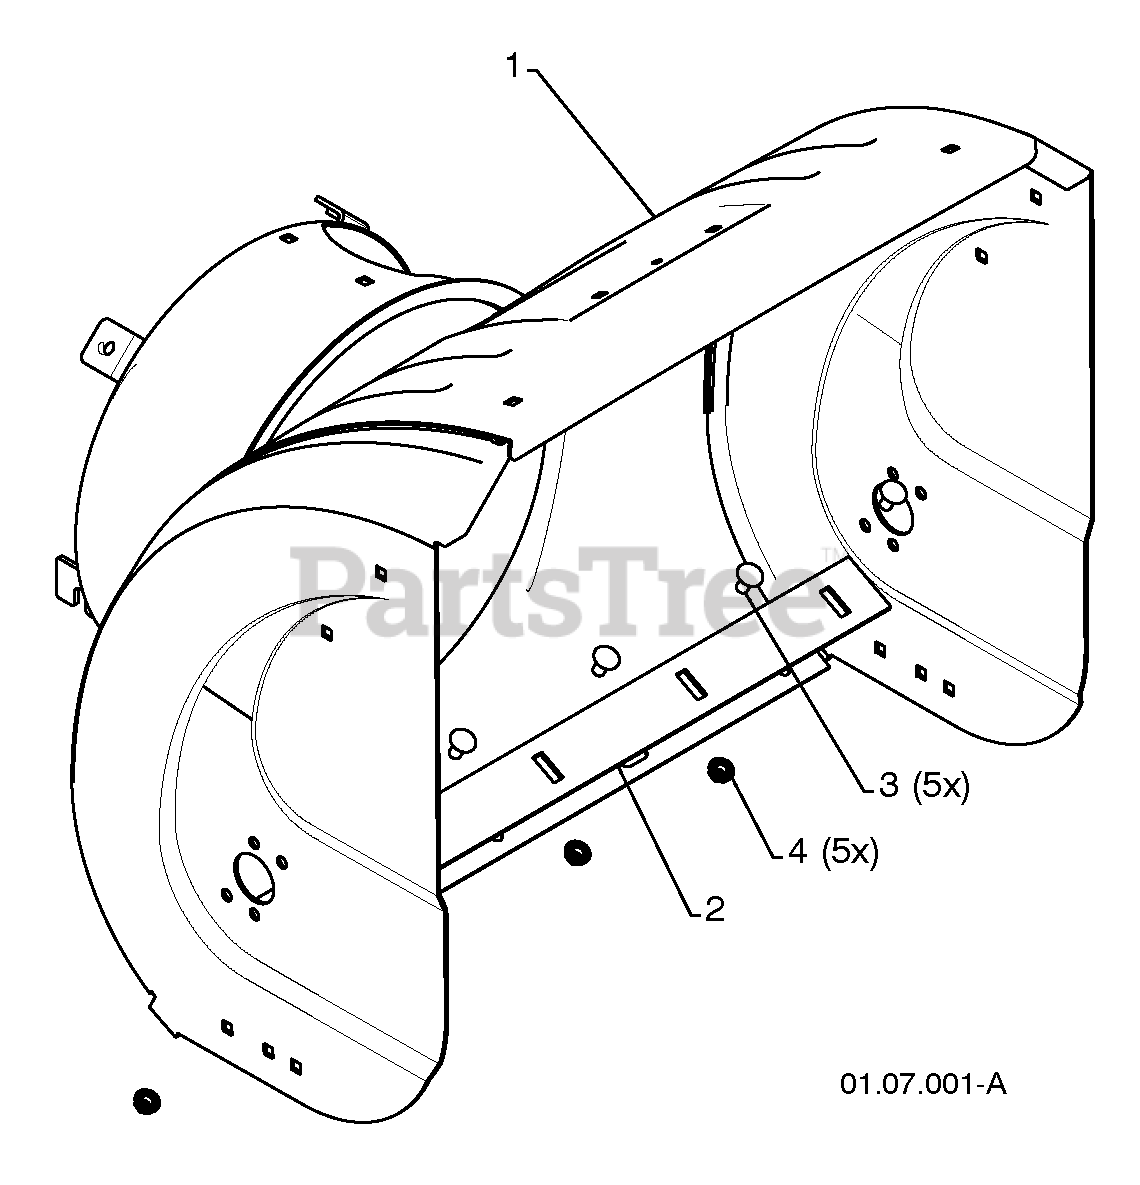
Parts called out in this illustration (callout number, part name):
1	AUGER HOUSING
2	SCRAPPER BAR
3	CARRIAGE BOLT 5/16-18 X .625
4	NUT 5/16-18
